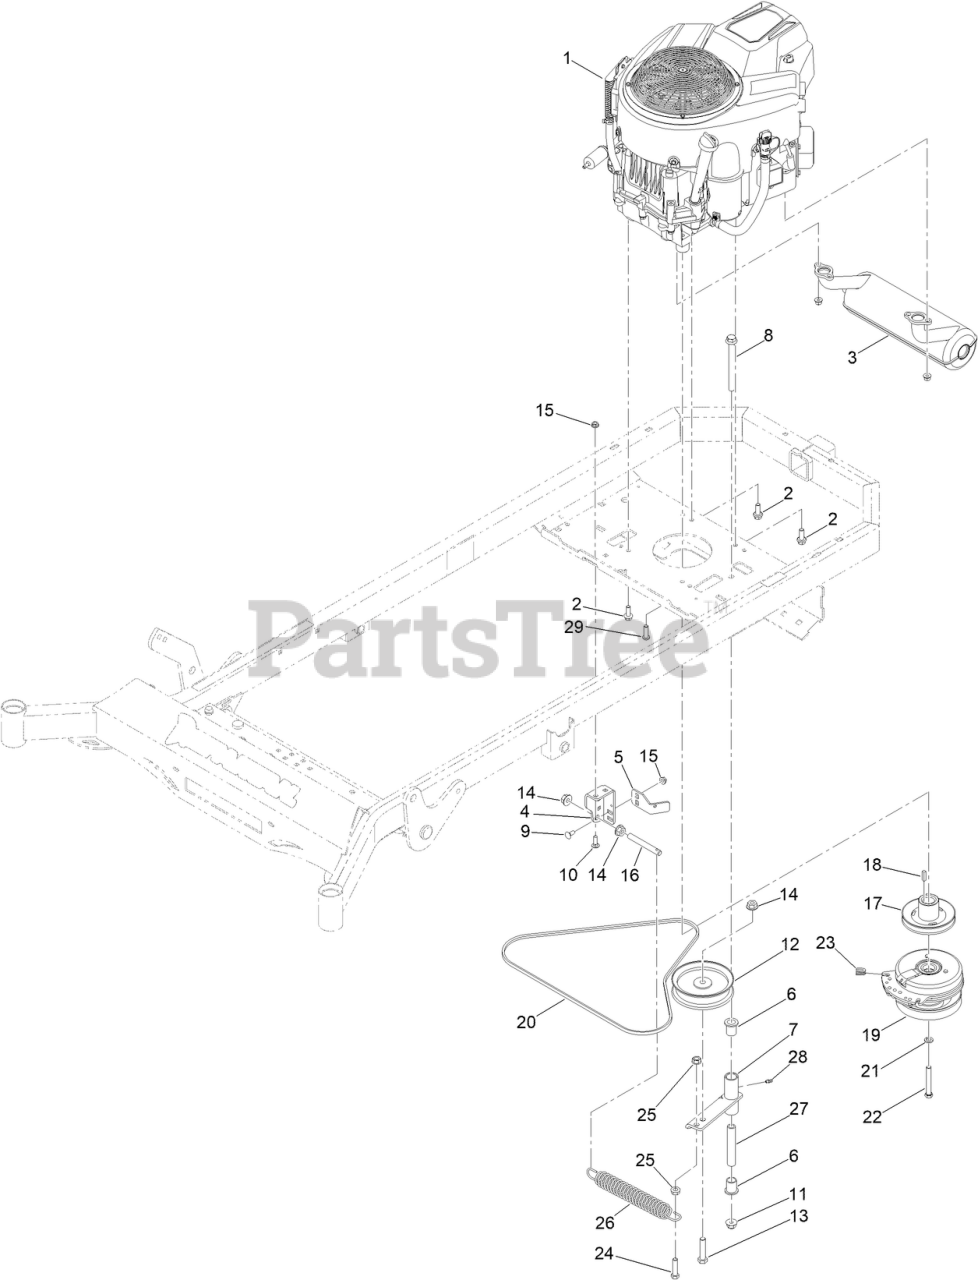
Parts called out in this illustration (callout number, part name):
1	27HP BRIGGS CXI ENGN W/OIL EXTEND
2	3/8-16 X 1-1/8 IND HWH W/SERR TRI LOB ZY
3	EXHAUST SYST BRIGGS 25/ 27HP ENGNS
4	MWR PUMP IDLER TENSIONING BRKTPAINTED
5	MOWER CLUTCH ANTI ROTATION BRACKET PAINT
6	3/4IN ID X15/16IN OD X 1-1/8IN FLNG BUSH
7	MWR PUMP IDLER ASSY PAINTED
8	1/2-13 X 5-1/2 HEX FLANGE BOLT GR 8 ZY
9	BOLT-CARR
10	BOLT-CARR
11	NUT-LOCK
12	5-3/4IN IDLER PULLEY 7/16IN SPACER ASSY
13	SCREW-HH
14	NUT-HHF
16	MWR PUMP IDLER SPRING TENSIONER
17	MWR HYDRAULIC PUMP DRIVE PULLEY (B-BELT)
19	WARNER PTO CLUTCH
20	TTQ RT PUMP B-BELT (61.25")
21	WASHER-LOCK
22	7/16-20 X 3 HEX C/S GR 8 ZC YELLOW
23	MWR CLUTCH ROTATION STOP BRKT SLEEVE
24	SCREW-HH
25	NUT-HF
26	MWR DECK SPRING
27	MWR INNER IDLER SPACER
28	1/4IN DRIVE TYPE GREASE FITTING YZ
29	3/8-16 X 1-1/4 PAN TORX (TRI-LOB) TRS ZC
